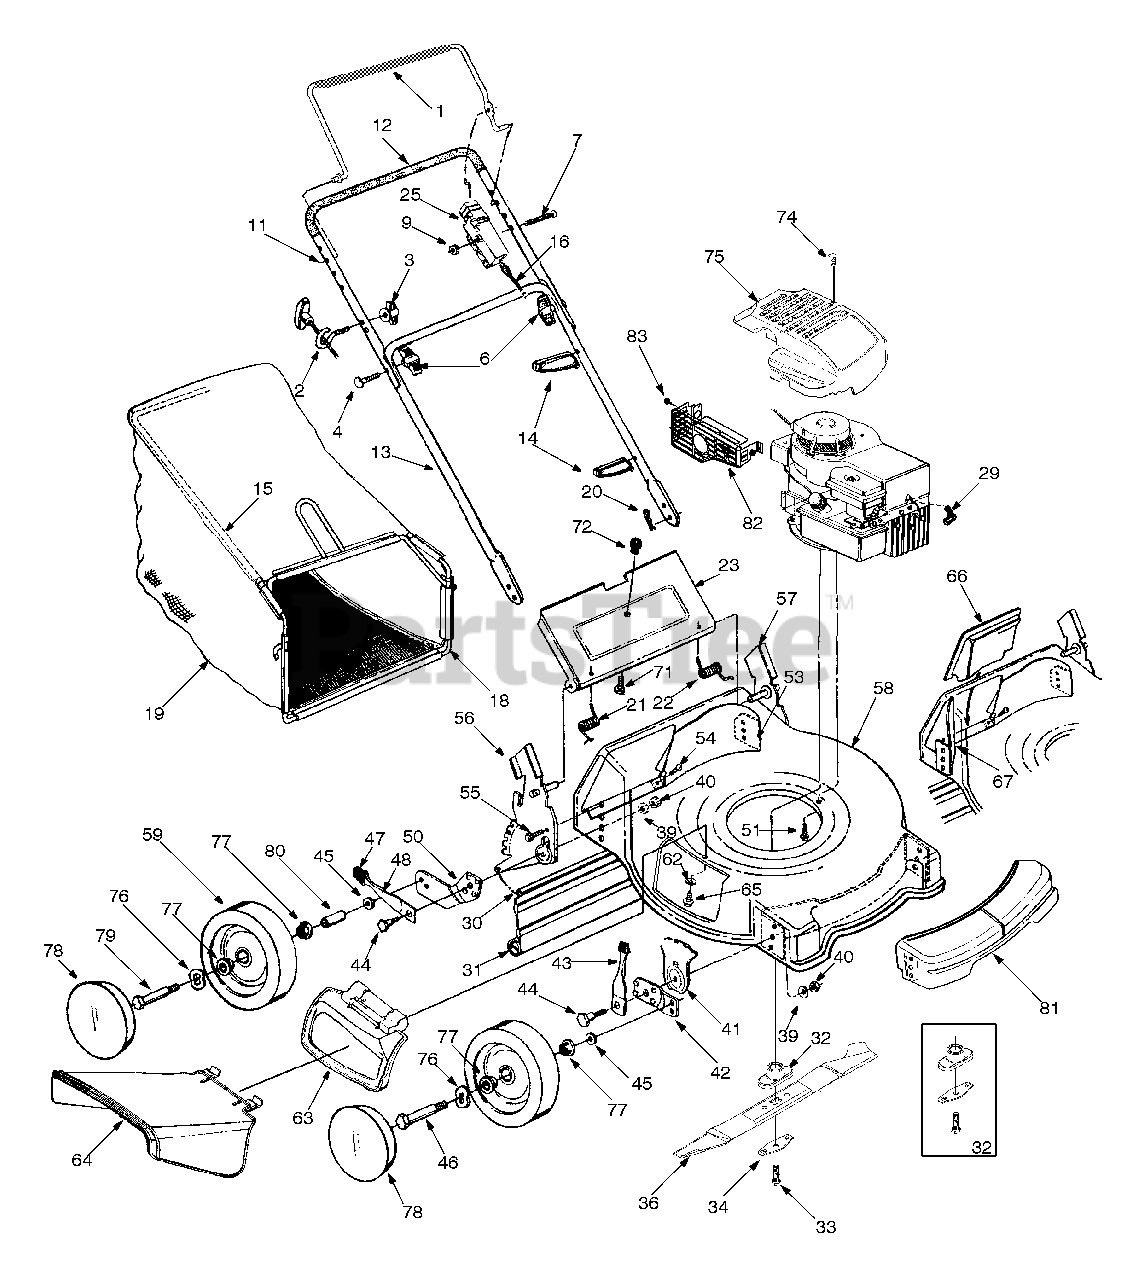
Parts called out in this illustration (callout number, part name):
1	Control Handle Assembly
3	Handle Knob 1/4-20 Thd.
4	Curved Hd. Bolt 5/16-18 x 2"
6	Hand Knob
7	Oval C-Sunk Mach. Scr.
9	Hex Lock Nut
14	Cable Tie
16	Control Cable
20	Internal Cotter Pin
21	Door Spring - R.H.
22	Door Spring - L.H.
29	Spark Plug Boot
30	Wire Rod
31	Rear Flap
32	Blade Adapter Kit
33	Hex Bolt 3/8-24 x 1.5"
34	Blade Bell Support
36	Mulching Blade 21"
39	Bell Washer
40	Hex Nut 3/8-16 Thd.
41	Height Adj. Plate
43	Spring Lever Assembly w/Knob
44	Shoulder Bolt
45	Bell Washer, 38" I.D. x .88"
46	Front Axle Bolt
47	Spring Lever Knob
54	Torx Mach. AB-Tap. Scr. 1/4 x .62"
55	Hex Lock Washer Hd. AB-Tap Scr.
58	Deck
59	Wheel Assembly Comp.
62	Bell Washer 1/4" I.D.
63	Hinged Mulching Plug
64	Chute Deflector: side discharge
65	Hex Hd. Self-Tap. Scr. 1/4-20 x .5
66	Mulching Baffle Plug
71	Truss Scr. #10-24 x .38
72	Knob: Chute Door
74	Hi-Lo Scr. #10 x 1.25
75	XTL Gray Shroud
76	Wave Washer
77	Ball Bearings
78	Hub Cap: Radial Spoke Gray
79	Rear Axle Bolt
80	Spacer
81	Cover: Front Deck Gray
82	Muffler Guard
83	Hex Washer Head Screw
